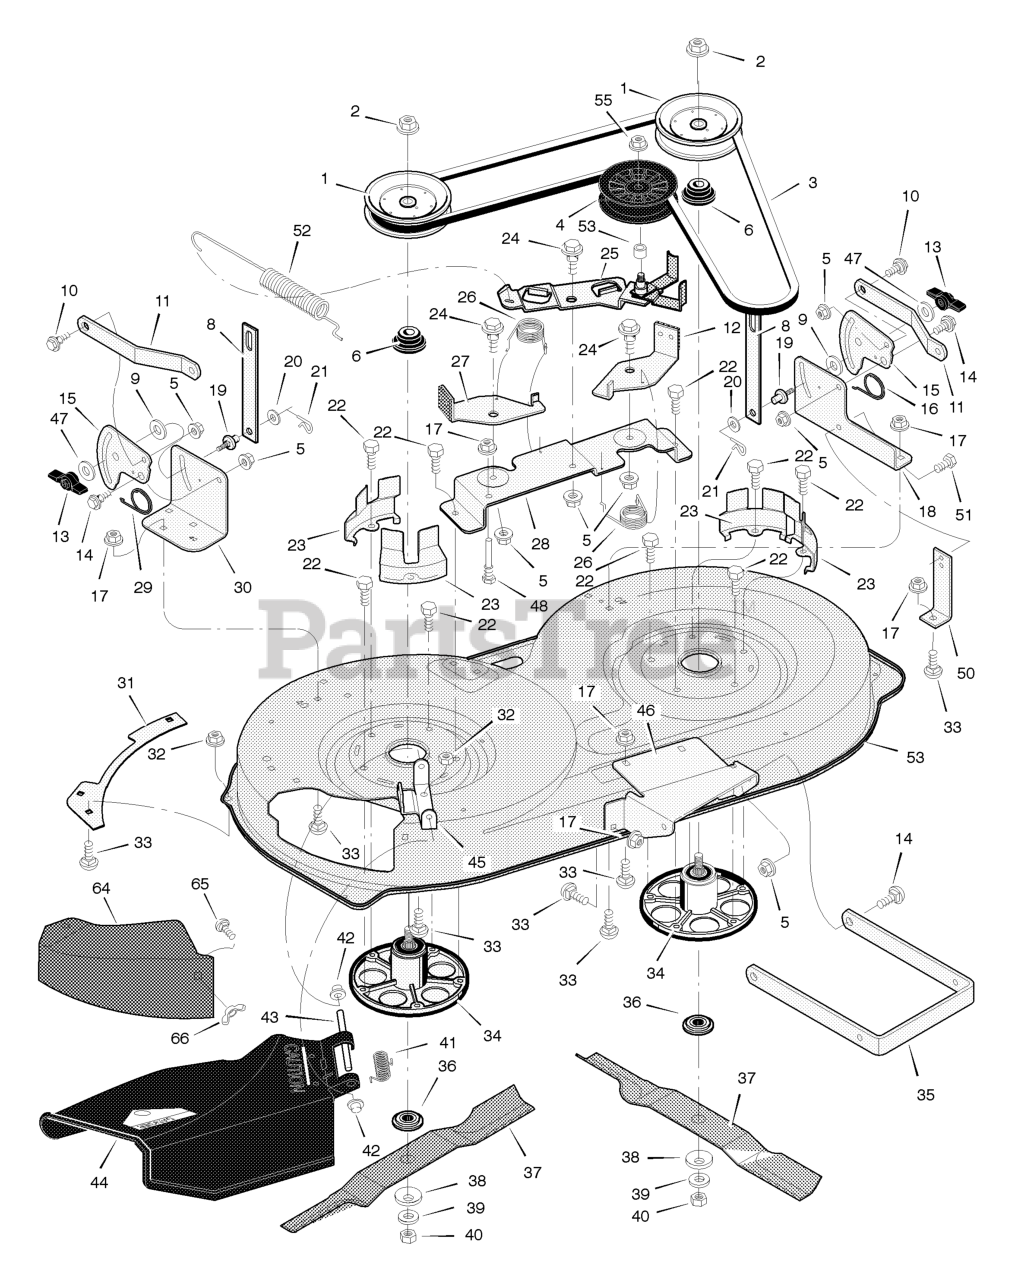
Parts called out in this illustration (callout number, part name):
1	Pulley, Jackshaft
2	Nut, Hex
3	Belt, Mower Drive
4	Pulley, Idler
5	Nut, Flange
6	Spacer, Pulley
8	Link, Lift
9	Pad, Friction
10	Bolt, Shoulder
11	Bracket, Suspension
12	Pad Assembly, Left Brake
13	Knob
14	Bolt, Shoulder
15	Plate, Suspension
17	Nut, Flange
18	Bracket, Suspension
19	Pin, Hanger
21	Pin, Cotter
22	Bolt
23	Cover, Pulley
24	Bolt, Shoulder
25	Arm, Idler
27	Pad Assembly, Right Brake
28	Bracket Assembly, Brake
30	Bracket, Suspension
31	Plate
32	Nut, Flange
33	Bolt, Carriage
34	Mandrell
35	Bracket, Suspension
36	Adapter, Blade
42	Cap, Push On
43	ROD, Deflector
44	Deflector Assembly
45	Bracket, Deflector
46	Bracket, Front Hanger
48	Guide, Belt
50	Bracket, Support
52	Spring, Extension
54	Housing, Blade
55	Nut, Flange
64	Cover, Mulch
65	Bolt
66	Wingnut
